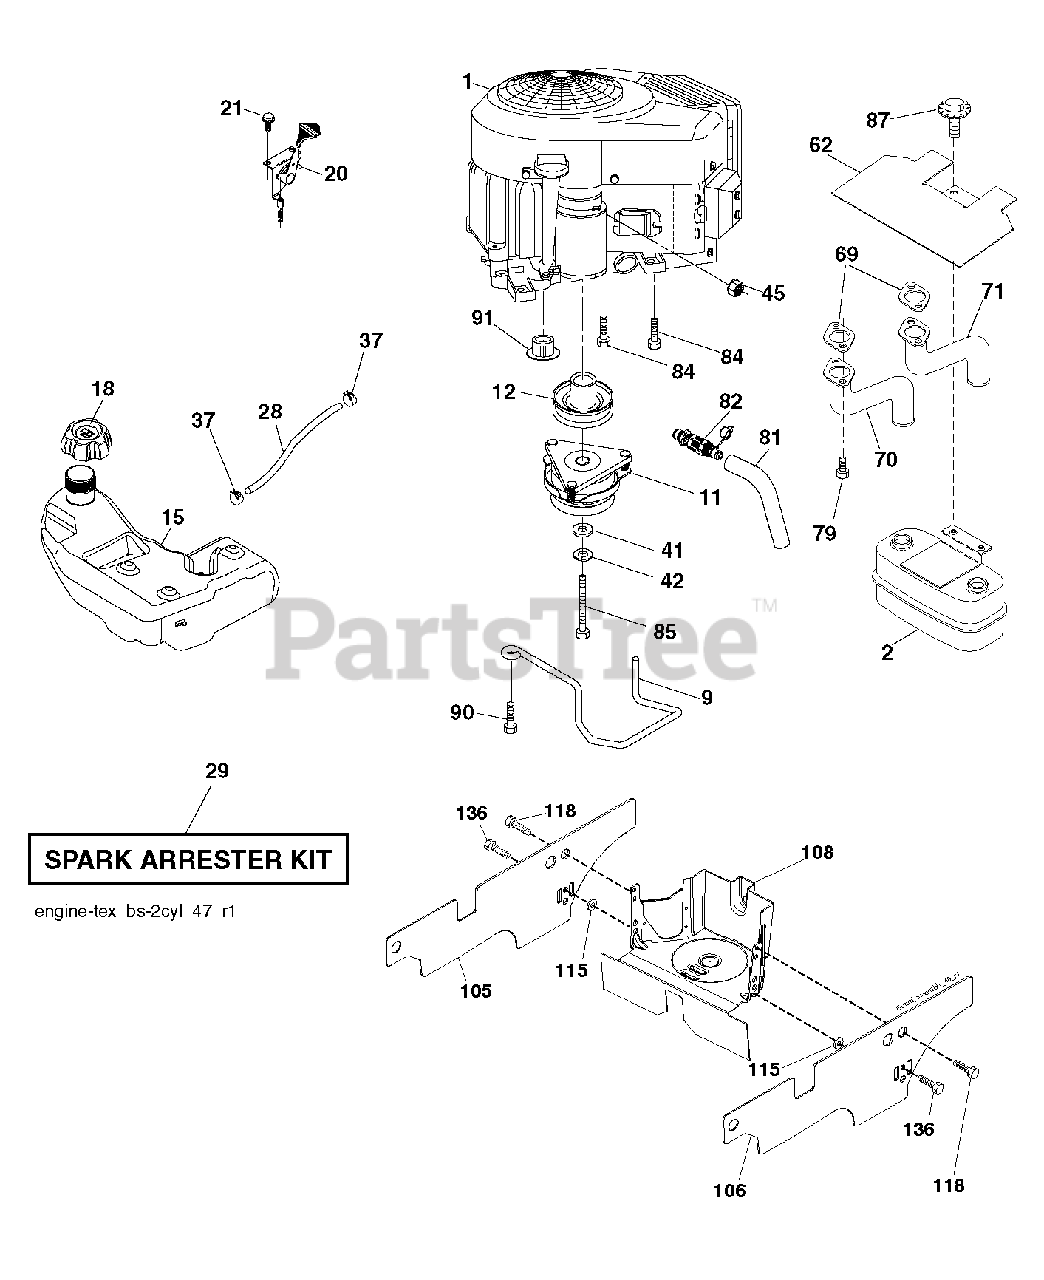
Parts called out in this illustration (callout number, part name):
2	MUFFLER.TWIN.CYL.LOW.TONE
9	KEEPER.BELT.ENGINE.4.2
11	CLUTCH.ELECTRIC.LT.48"*
12	PULLEY.ENGINE.TUFFTORQ
15	TANK.FUEL.4GAL
18	CAP.ASM.FUEL.TANK.3"BLACK
20	CONTROL.TH/CK.COBRA.B&S.TWN.
21	SCREW.#10 X 0.750.BOS THREAD
28	LINE.FUEL.20
29	ARRESTER SPARK (OPTIONAL)
37	HOSE CLAMP
42	LOCKWASHER
45	NUT
62	SHIELD.HEAT.MUFFLER
69	GASKET.MUFFLER
70	TUBE MANIFOLD LH
71	EXHAUST TUBE RH
79	SCREW.SOCKET.HEAD.5/16-18
81	TUBE, DRAIN OIL ASM.
82	VALUE.OIL.DRAIN
84	SCREW.3/8-16
85	BOLT HEX 7/16-20X4-1/4"
87	BOLT 5/1618UNC X 3/4 W/ SEMS
90	SCREW 3/8-16X1
91	BUSHING.1.375OD
115	PALNUT 1/4
118	SCREW, 5/16-18 X 1/2
136	SCREW.1/4-20X5/8
